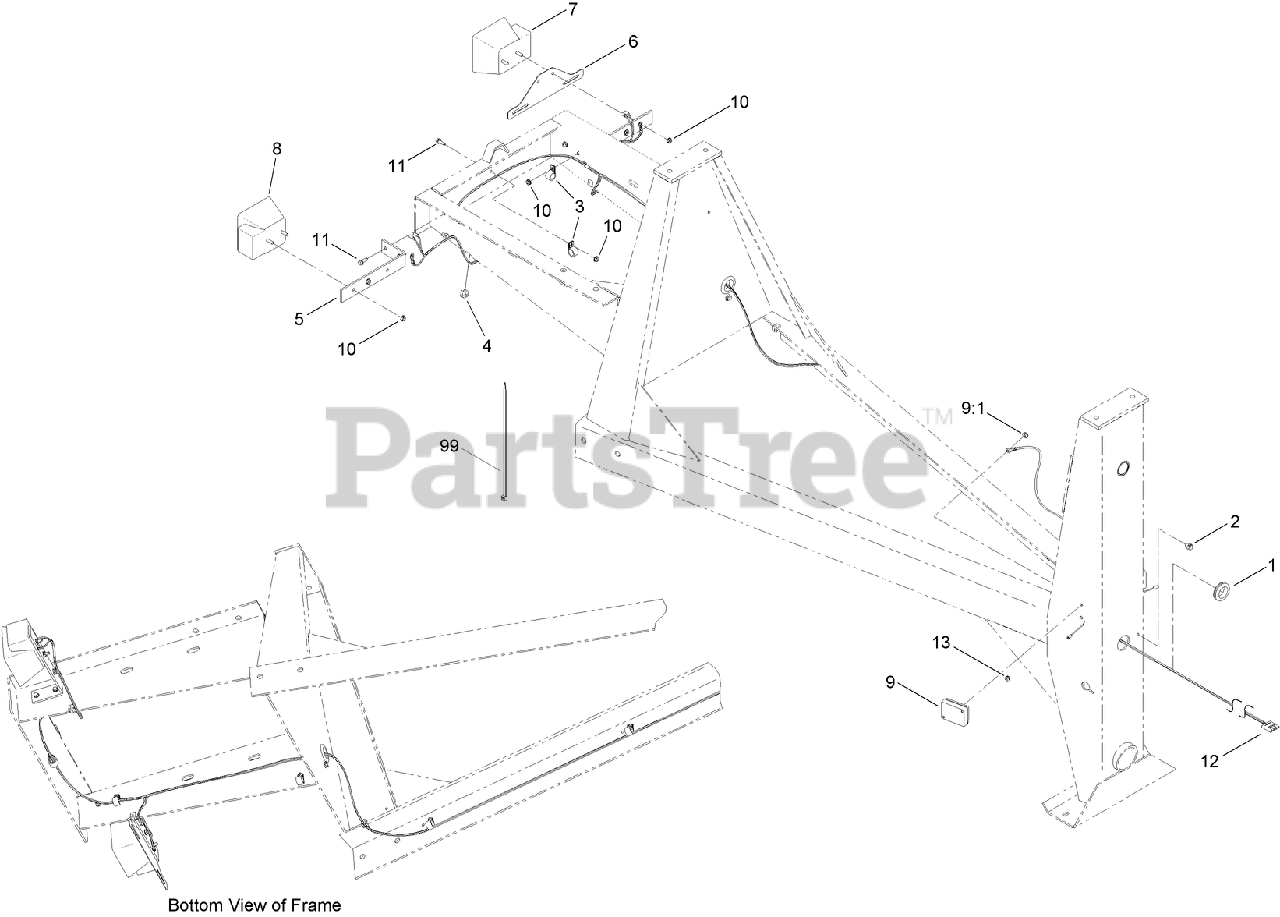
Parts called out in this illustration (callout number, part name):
1	GROMMET
2	CLIP-TIE
3	CLAMP-CABLE
4	CLIP-EDGE
5	BRACKET-UNIVERSAL
6	HOLDER-PLATE, LICENSE
7	LIGHT-TAIL, LH
8	LIGHT-TAIL, RH
9	LAMP-MARKER, FRONT SIDE
9:1	NUT-KEPS
10	NUT-KEPS
11	SCREW-HHF
12	HARNESS-WIRE
13	GROMMET
99	TIE-CABLE
